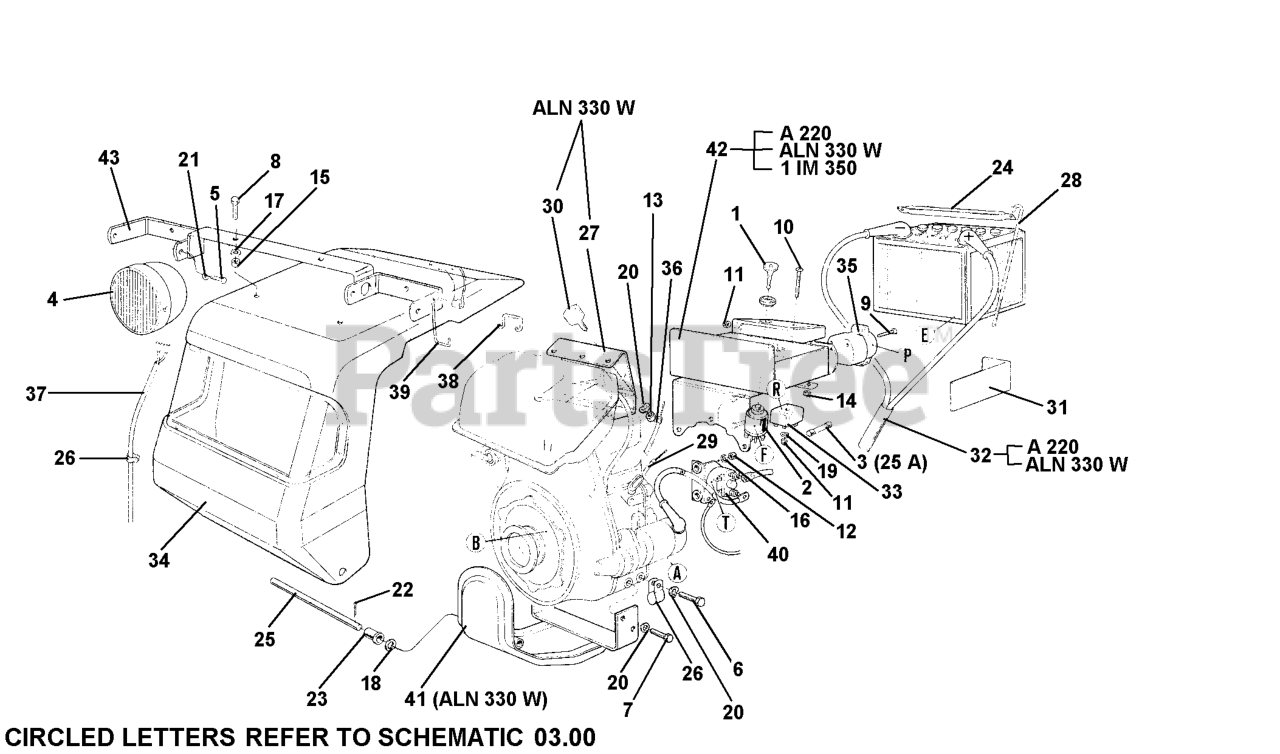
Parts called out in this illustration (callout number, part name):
3	FUSE 6 X 25 25A
5	SCREW TE M6 X 14
6	SCREW TE M8 X 12
7	SCREW M8 X 16
8	SCREW M8 X 25
9	SCREW TCCEI M4 X 30
10	SCREW TC M4 X30 UNI 6107
14	NUT, SELF LOCKING M6
15	NUT, SELF LOCKING M8
16	WASHER, FLAT 6.4
17	FLAT WASHER 9 X 24 UNI 6593
18	FLAT WASHER 10.5 X 21
19	LOCK WASHER B 4.3
20	WASHER, LOCK 8.4
21	WASEHR, LOCK AZ 6.4 DIN 6798
22	PIN, COTTER A 3 X 20 UNI 1336
24	BATTERY BRACKET
25	PIN, COUPLING
26	CLAMP ENGINE
27	CONNECT. UPPER ELECTRIC ST.
28	BATTERY TIEROD
29	CABLE & SHEATH,ACCEL.LOMBAR
31	ANTISHOCK BAT
32	ELECTRIC START CABLES MC 715
34	HOOD, PLASTIC, COMPLETE
35	7-POLE SOCKET
36	SHEATH CABLE
37	COVER CABLES
38	ELECTRIC STARTER HOOK
40	BOSCH RELAY 0332002160
41	HOOD LOWER COUPLING
42	BATTERY SUPPORT COMPL.
43	LIGHT SUPPORT
